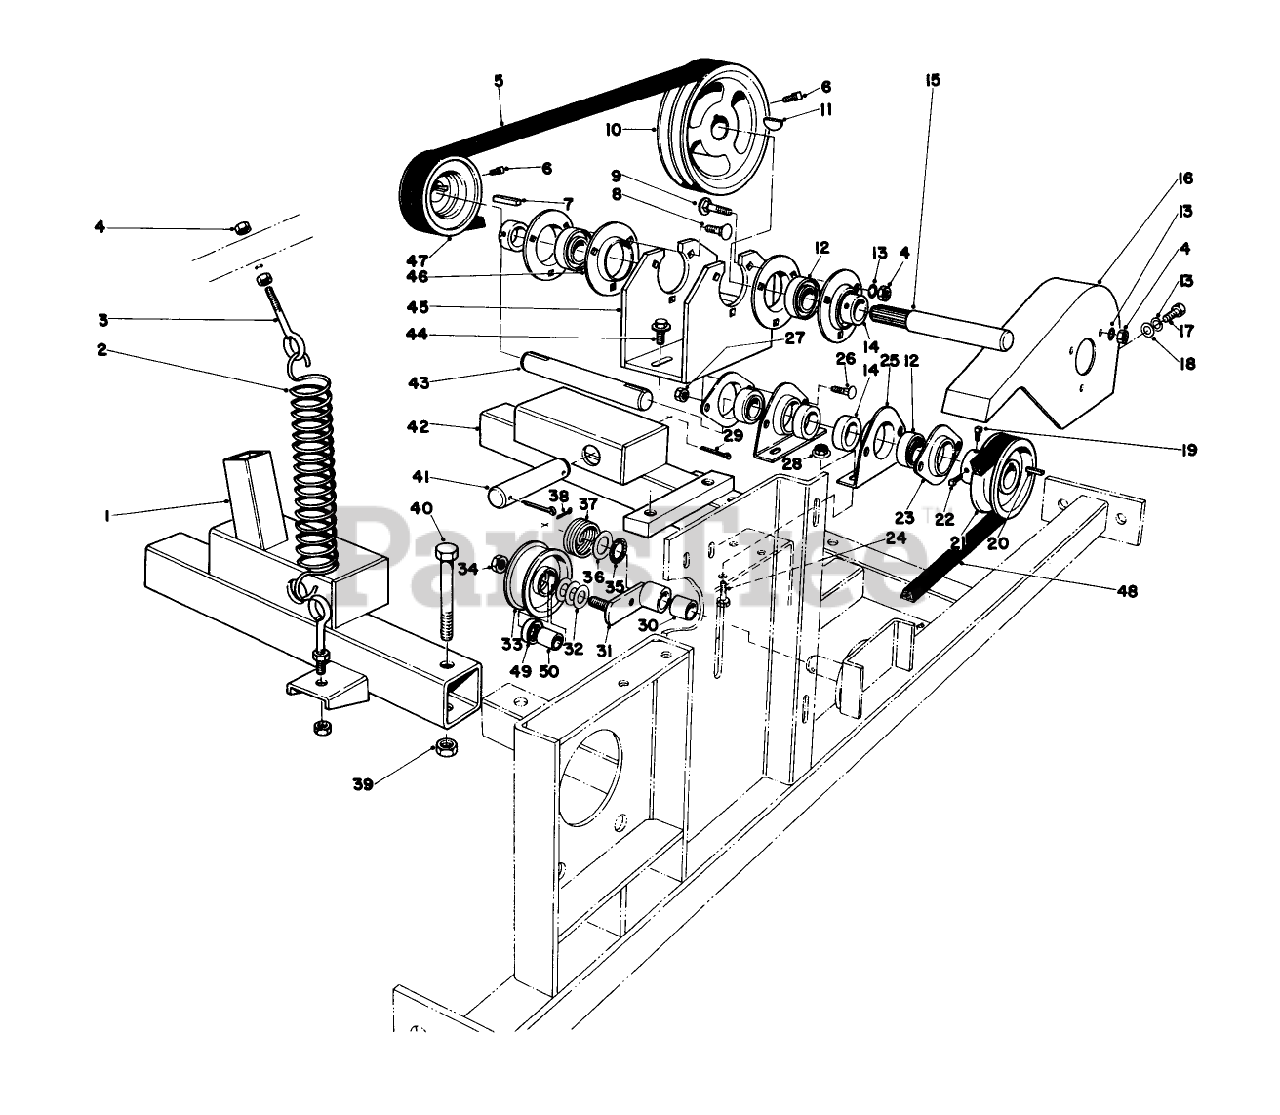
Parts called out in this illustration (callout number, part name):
1	Adapter R.H.
2	Extension Spring
3	Eyebolt
4	NUT-HEX
5	V-BELT
6	SCREW-SET, SQH
8	SCREW-CARR
9	BOLT-CARR
10	JACKSHAFT PULLEY
11	KEY-WOODRUFF
12	Bearing (Incl. Ref. #14)
13	WASHER-LOCK/SP
14	COLLAR-LOCK, BEARING
15	JACKSHAFT
16	Belt Shield
17	SCREW-HH
18	WASHER-PLAIN
19	5/16-18 X 1/2 SQ HD
21	SHEAVE 60103
22	SCREW-SQH
23	Flange
24	SCREW-HH
25	FLANGE
26	BOLT-CARR
27	NUT-HF
28	NUT-HHF, WHIZ
29	3/32 X 1-3/4 LG COTTER
30	BUSHING 16162
31	Idler Arm (Incl. Ref. #30)
32	WASHER-FLAT
33	Idler Pulley
34	LOCKNUT 6239
35	Felt Washer
36	Washer
37	Spring-Torsion
38	PIN-COTTER
39	NUT-LOCK, CONE
40	SCREW-HH
42	Adapter L.H.
43	JACKSHAFT
44	SCREW-HHF
45	JACKSHAFT SUPPORT
46	FLANGE
47	JACKSHAFT PULLEY
48	V-BELT
49	Bearing
50	Sleeve
